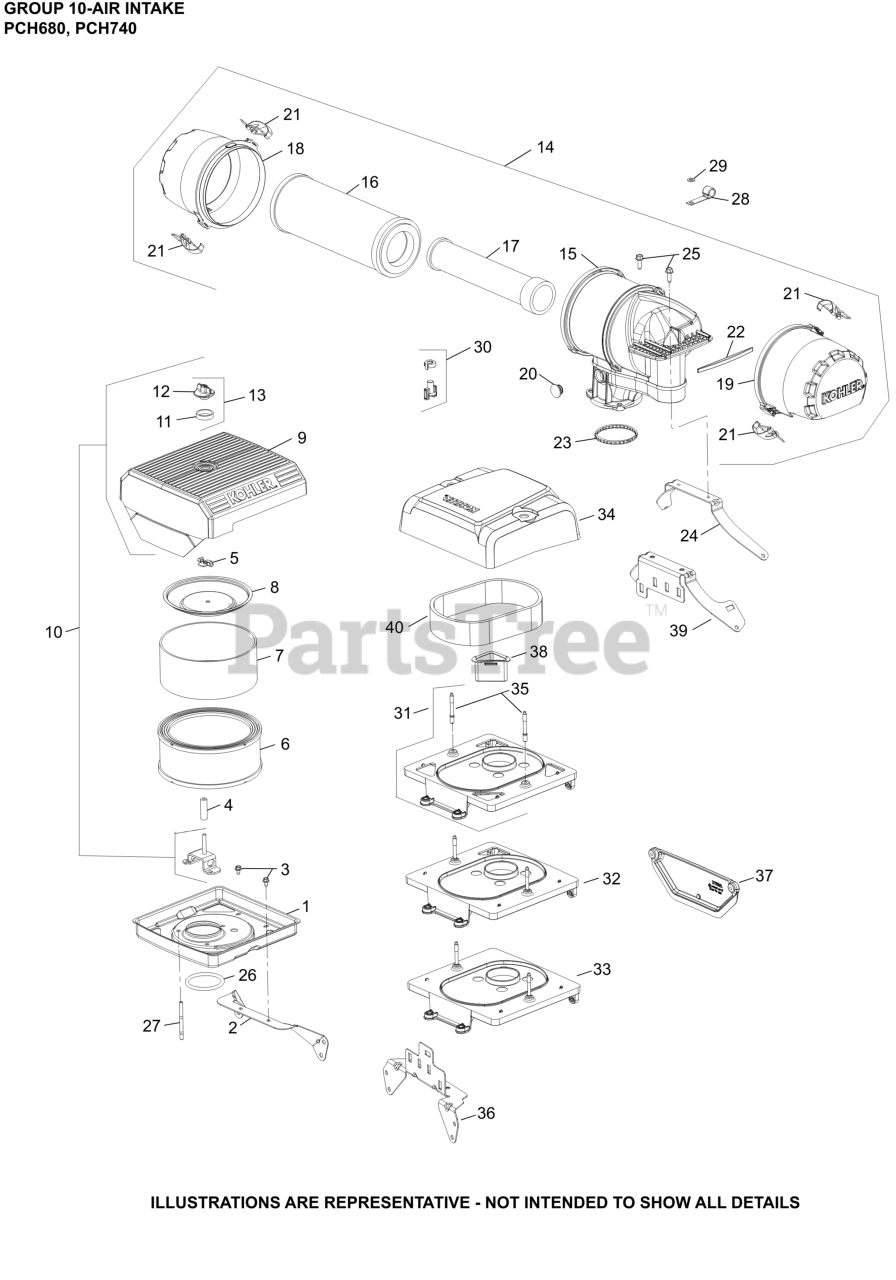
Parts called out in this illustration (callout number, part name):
1	BASE, AIR CLEANER
2	AIR CLEANER BRACKET
3	SCREW, THREAD FORMING
5	NUT, WING
6	AIR FILTER ELEMENT
7	PRE-CLEANER (HIGH)
8	COVER, INNER AIR CLEANER
9	COVER, AIR CLEANER
10	KIT, AIR CLEANER COVER
12	KNOB, COVER
13	KIT, KNOB W/SEAL
26	O-RING, AIR CLEANER BASE
27	STUD, LOW PROFILE A/C
28	CLIP, CABLE
29	WASHER, FLAT 1/4" (O.D. 1/2")
NI	KIT, INTAKE MANIFOLD GASKET
NI	COVER, AIR CLEANER
NI	KIT, AIR CLEANER COVER
